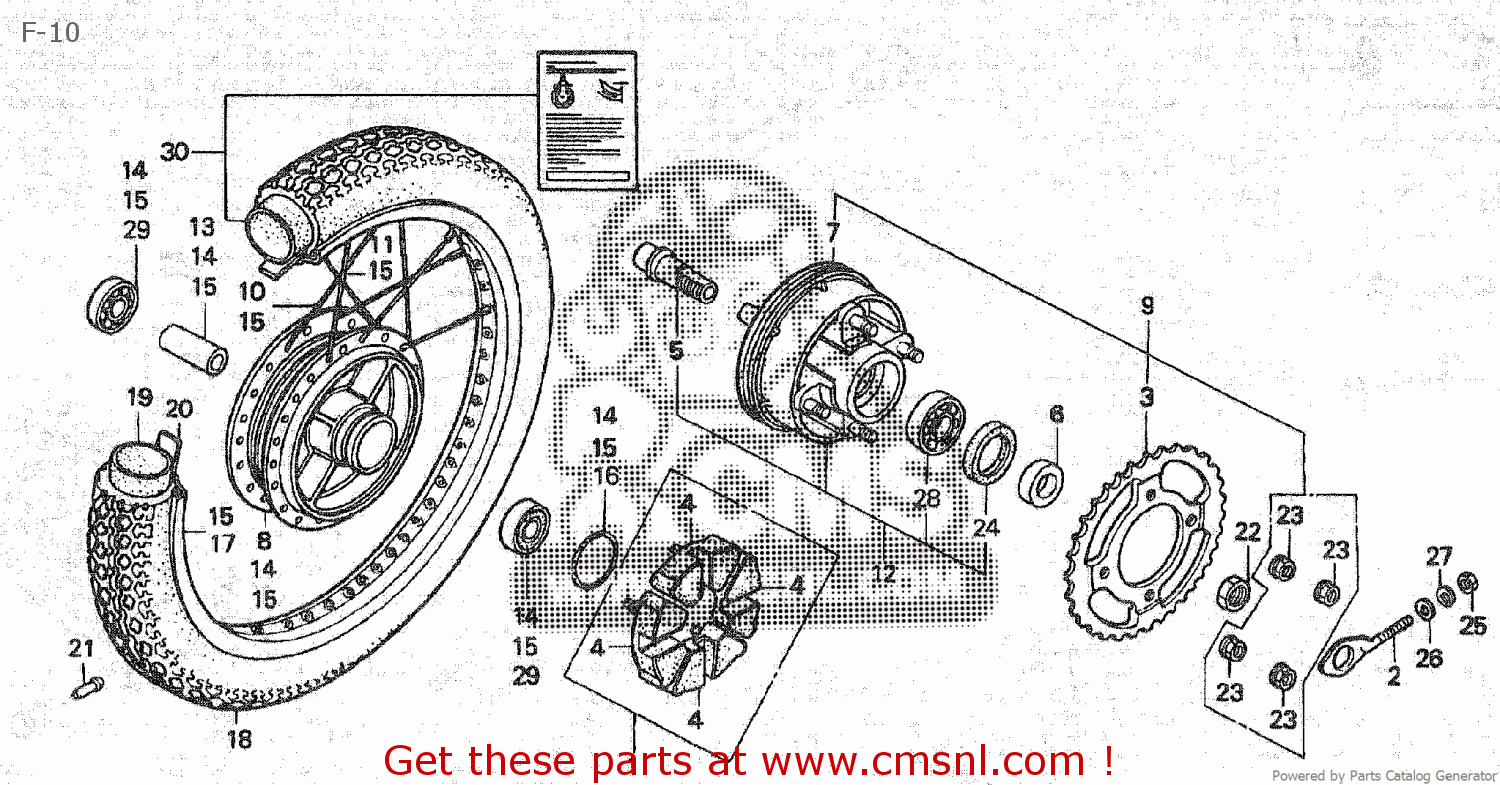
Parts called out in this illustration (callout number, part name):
2	ADJUSTER,L.CHAIN
3	SPROCKET,FINAL DR
4	DAMPER REAR WHEEL
5	SLEEVE,RR.AXLE
6	COLLAR,SLEEVE
7	FLANGE,FINAL
8	HUB,RR WHEEL
9	FLANGE,FINAL
10	SPOKE SET,B10X121
11	SPOKE,B10X120.5
13	COLLAR,REAR AXLE
16	O-RING,40.5X3
17	RIM,RR.WHEEL
18	TIRE,SNOW
19	TUBE,TIRE
20	FLAP,TIRE
21	PIN,SPIKE
22	NUT, REAR AXLE
23	NUT,HEX.,8MM
24	OIL SEAL,27X40X6
25	NUT,HEX 6MM
26	WASHER,PLAIN, 6MM
27	WASHER,SPRING,6MM
28	B/BRG RAD N/COM
29	B/BRG RAD N/COM
